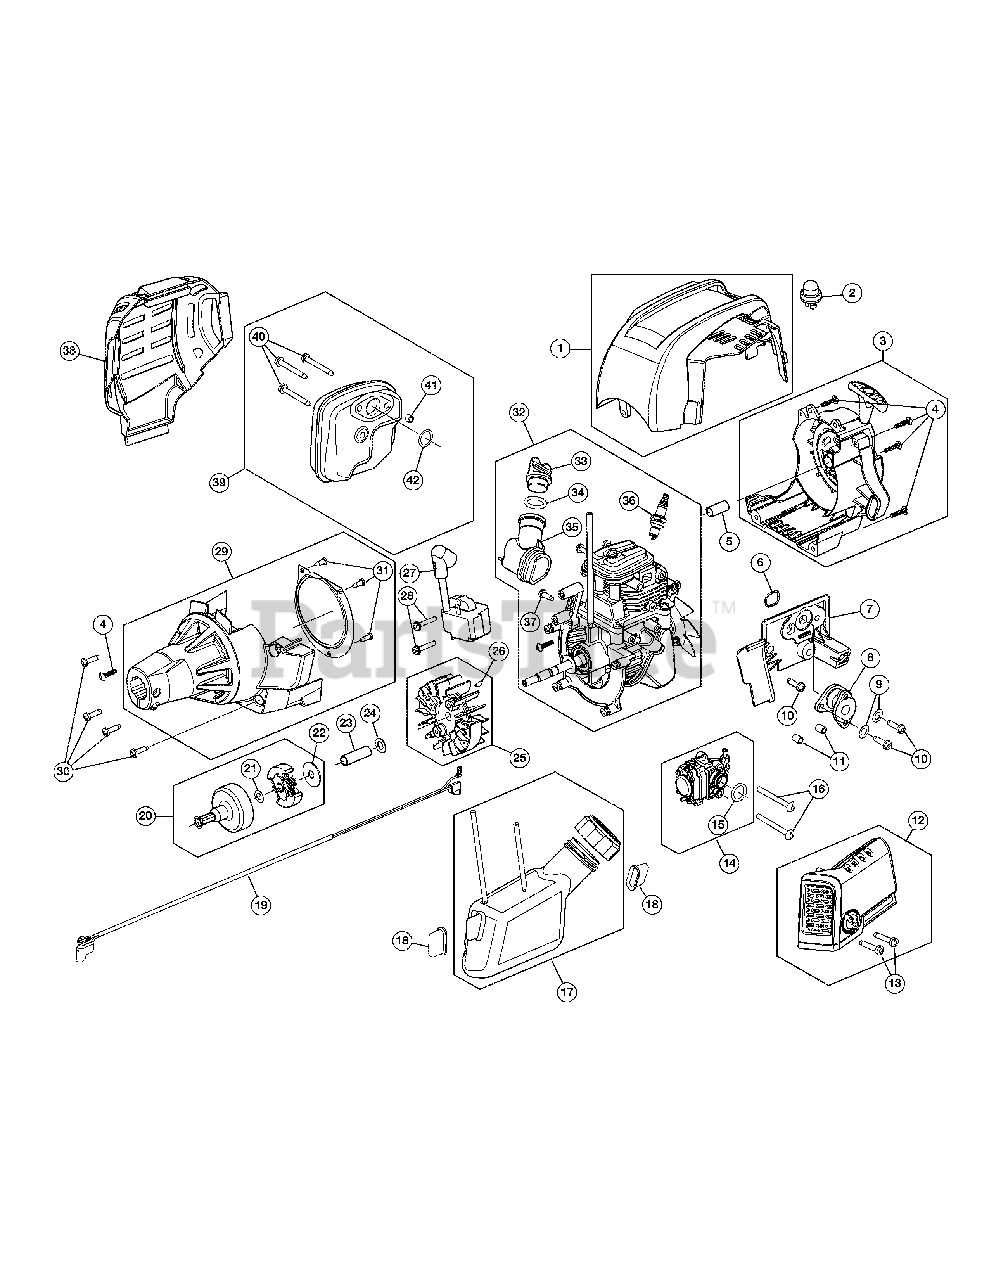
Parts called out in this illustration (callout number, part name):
1	Top Housing Assembly
2	Air Purge Primer
3	Starter Housing Assembly
5	Electric Start Adapter
7	Intake Port
8	Boot Assembly
11	Aircleaner Spacer
12	Aircleaner Assembly
14	Carburetor Assembly
17	Fuel Tank Assembly
18	Fuel Tank Pad
20	Clutch Assembly
21	Thrust Washer
22	Clutch Washer
23	Power Shaft Spacer
24	Thrust Washer
25	Flywheel Assembly
27	Module Assembly
29	Clutch Cover Assembly
30	Screw
32	Shortblock Assembly
33	Oil Fill Plug
35	Oil Fill Tube
36	Spark Plug
38	Muffler Housing
39	Muffler Assembly
40	Screw
41	Aircleaner Spacer
42	Muffler Gasket
